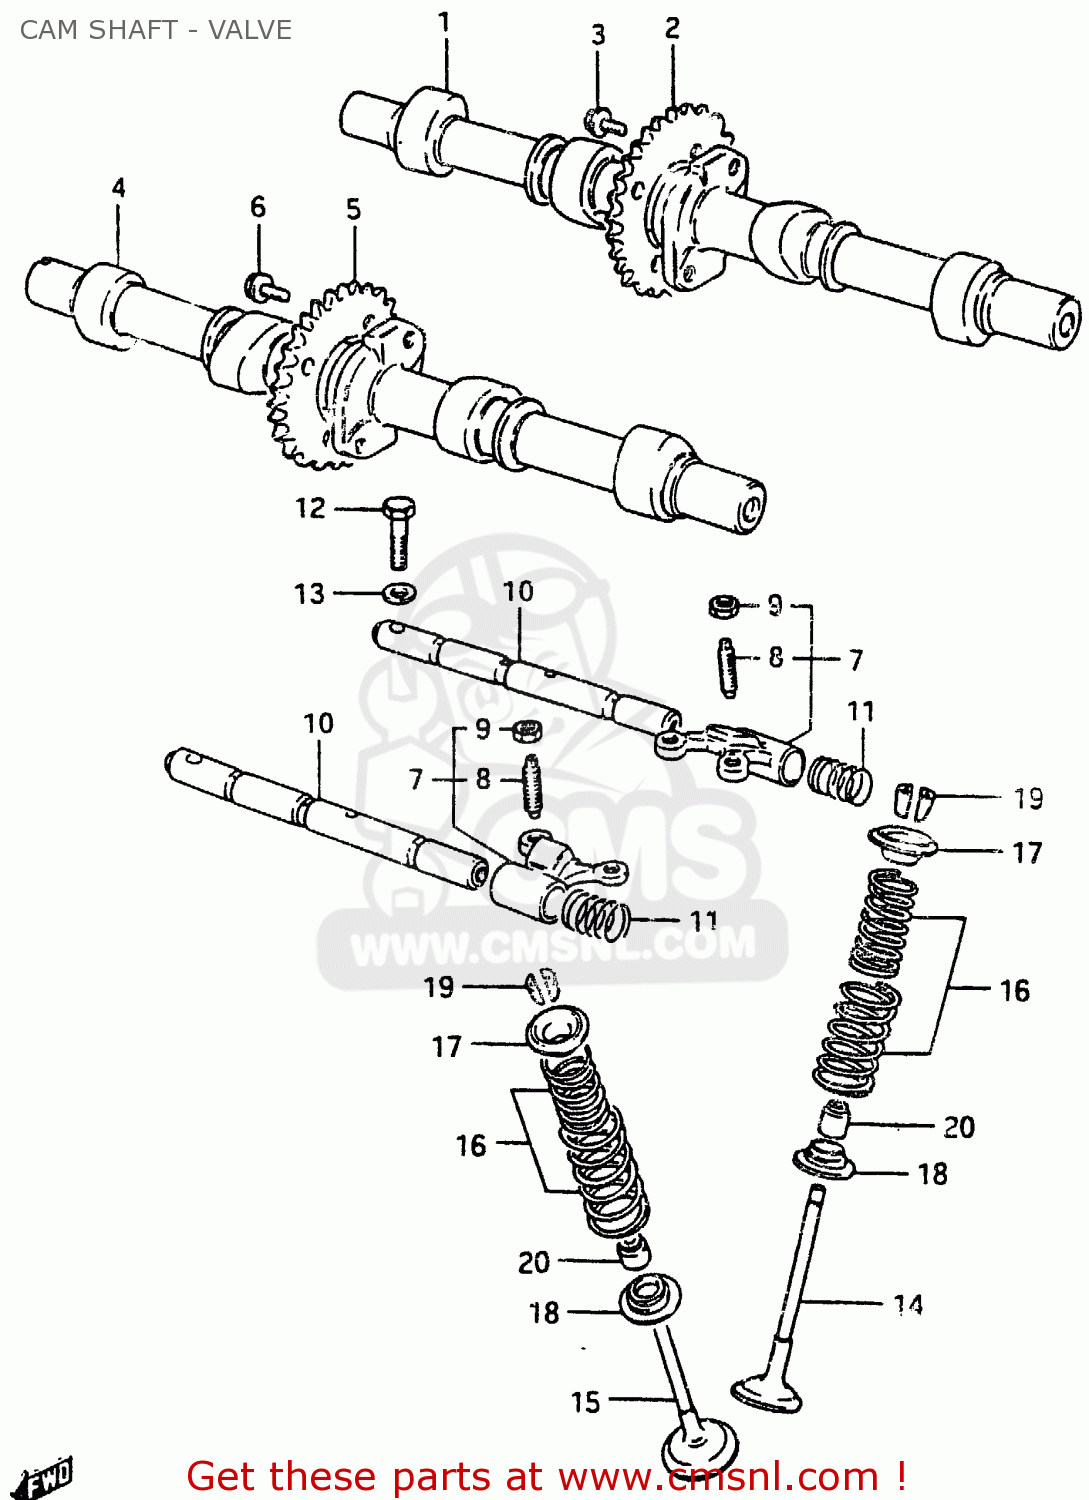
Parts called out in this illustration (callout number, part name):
1	CAMSHAFT,INTAKE
2	SPROCKET,INTAKE CAMSHAFT
3	BOLT(7X11)
4	CAMSHAFT,EXHAUST
5	SPROCKET,EXHAUST CAMSHAFT
6	BOLT(7X11)
7	ARM,VALVE ROCKER
8	SCREW,TAPPET ADJUSTING
9	NUT,ADJUSTING
10	SHAFT,VALVE ROCKER
11	SPRING
12	BOLT
13	WASHER, LOWER
14	VALVE,INTAKE
15	VALVE,EXHAUST
16	SPRING SET,VALVE
17	RETAINER,VALVE SPRING
18	SEAT,VALVE SPRING
19	COTTER VALVE
20	OIL SEAL
